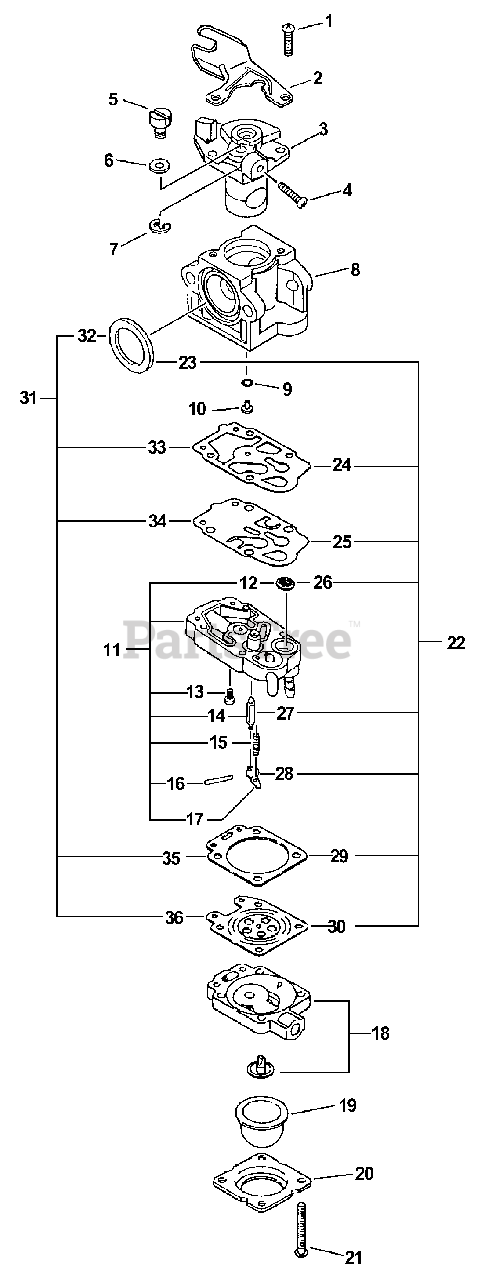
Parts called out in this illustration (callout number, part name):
2	BRACKET, THROTTLE CABLE
3	THROTTLE VALVE ASSY
8	BODY, CARBURETOR
10	JET, MAIN
11	BODY ASSY, PUMP
12	STRAINER
14	VALVE, INLET NEEDLE
15	SPRING, METERING LEVER
16	PIN, METERING LEVER
17	LEVER, METERING
18	BODY ASSY, PURGE
19	BULB, PURGE
20	RETAINER, PURGE BULB
22	REPAIR KIT, CARBURETOR
23	SEAL
24	GASKET, PUMP
25	DIAPHRAGM, PUMP
26	STRAINER
27	VALVE, INLET NEEDLE
28	LEVER, METERING
29	GASKET, METERING
30	DIAPHRAGM, METERING
31	GASKET / DIAPHRAGM KIT
32	SEAL
33	GASKET, PUMP
34	DIAPHRAGM, PUMP
35	GASKET, METERING
36	DIAPHRAGM, METERING
